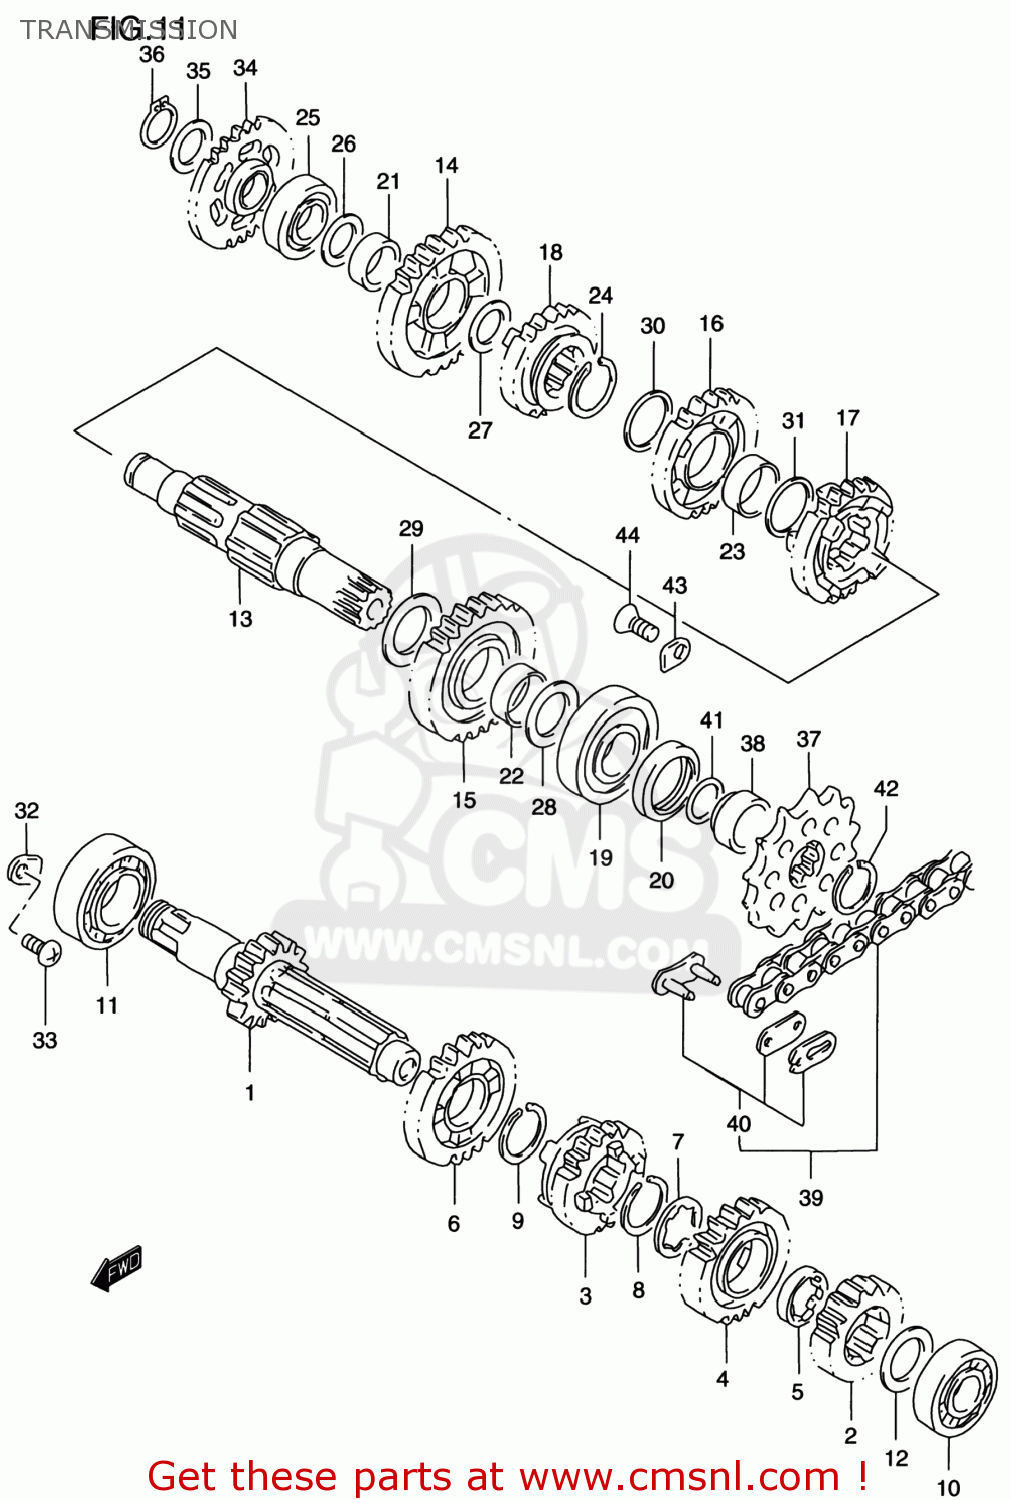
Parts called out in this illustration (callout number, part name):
1	SHAFT,COUNTER(NT:15)
2	GEAR,SECOND DRIVE (NT:17)
3	GEAR,THIRD DRIVE (NT:19)
4	GEAR,FOURTH DRIVE (NT:21)
5	BUSH,4TH DRIVE GEAR
6	GEAR,5TH DRIVE(NT:23)
7	WASHER,LOCK
8	CIRCLIP
9	CIRCLIP
10	BEARING
11	BEARING
12	WASHER,THRUST
13	SHAFT,DRIVE
14	GEAR,1ST DRIVEN(NT:27)
15	GEAR,SECOND DRIVEN (NT:25)
16	GEAR,THIRD DRIVEN (NT:23)
17	GEAR,FOURTH DRIVEN (NT:21)
18	GEAR,5TH DRIVEN(NT:20)
19	BEARING(22X56X15)
20	SEAL,OIL(28X38X6)
21	BUSH(20X24X10)
22	BUSH(25X28X10)
23	BUSH(25X28X10)
24	CIRCLIP
25	BEARING(17X40X12)
26	WASHER,THRUST
27	WASHER
28	WASHER
29	WASHER
30	WASHER
31	SHIM
32	RETAINER
33	SCREW
34	GEAR,KICK STARTER IDLE
35	SHIM
36	CIRCLIP,17MM
37	SPROCKET(NT:14)
38	SPACER,ENGINE SPROCKET
39	CHAIN ASSEMBLY DID520DM.11
40	JOINT SET,CHAIN
41	O RING(D:1.9,ID:19.8)
42	CIRCLIP
43	RETAINER,COUNTER BEARING,R
44	SCREW
